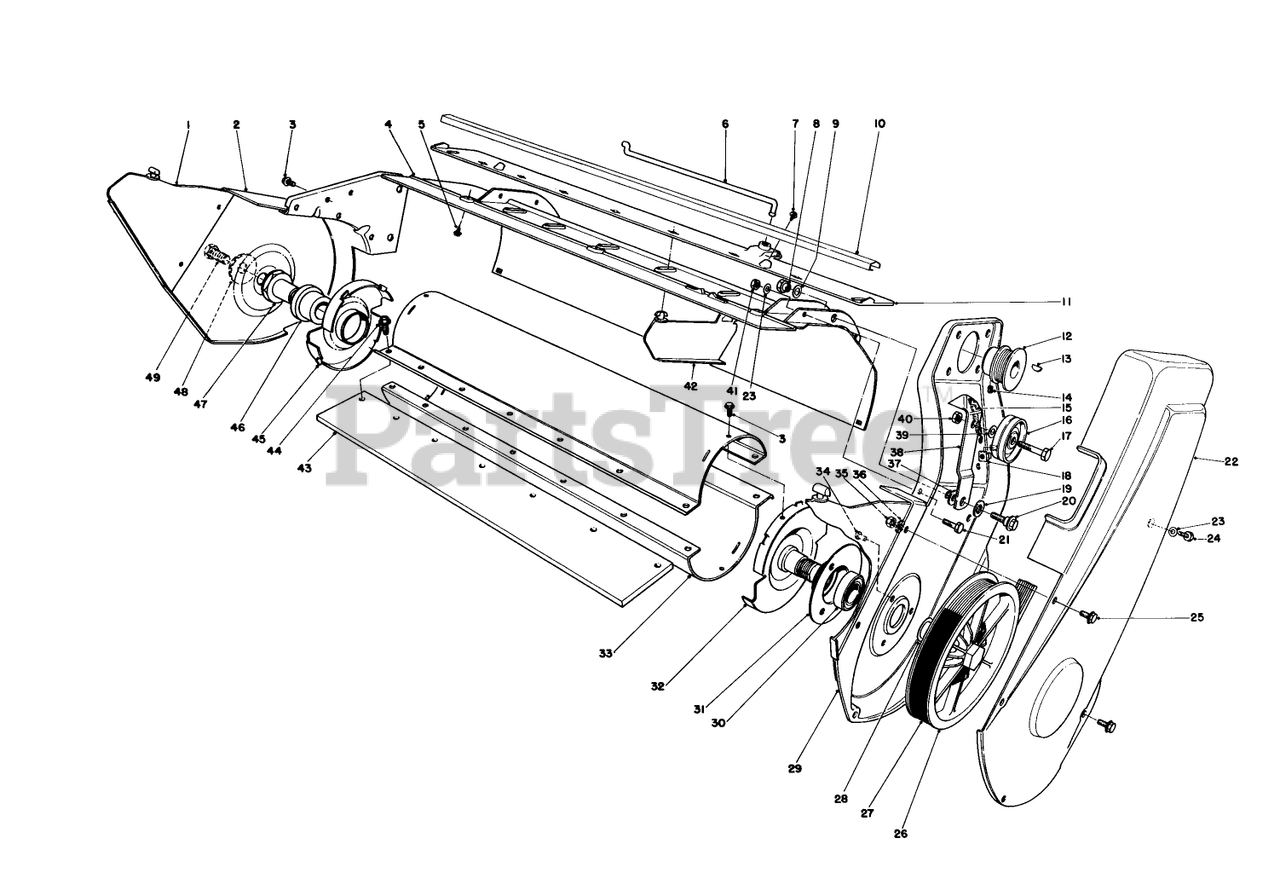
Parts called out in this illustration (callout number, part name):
3	SCREW
5	SCREW-HWHTF
7	10-16 X 3/8 THDG SCREW
9	WASHER
13	KEY-WOODRUFF
14	SCREW-HSH
15	IDLER SPRING
16	IDLER PULLEY
17	SCREW-HH
18	TINNERMAN NUT
19	WASHER
20	SCREW-SHOULDER
21	SCREW-HH
23	WASHER-FLAT
24	1/4-20 X 5/8 CAPSCREW
25	SCREW-SHWH
26	PULLEY ASM ROTOR
27	BELT - DRIVE
28	WASHER
30	BEARING-BALL
31	FLANGE-BEARING
34	RIVET
35	NUT-LOCK, NI
37	WASHER-PIVOT
38	IDLER ARM
39	WASHER-FLAT
40	NUT-LOCK, NI
41	NUT-LOCK, CONE
43	ROTOR BLADE
46	ROTOR BUSHING
48	WASHER-BELLEVILLE
